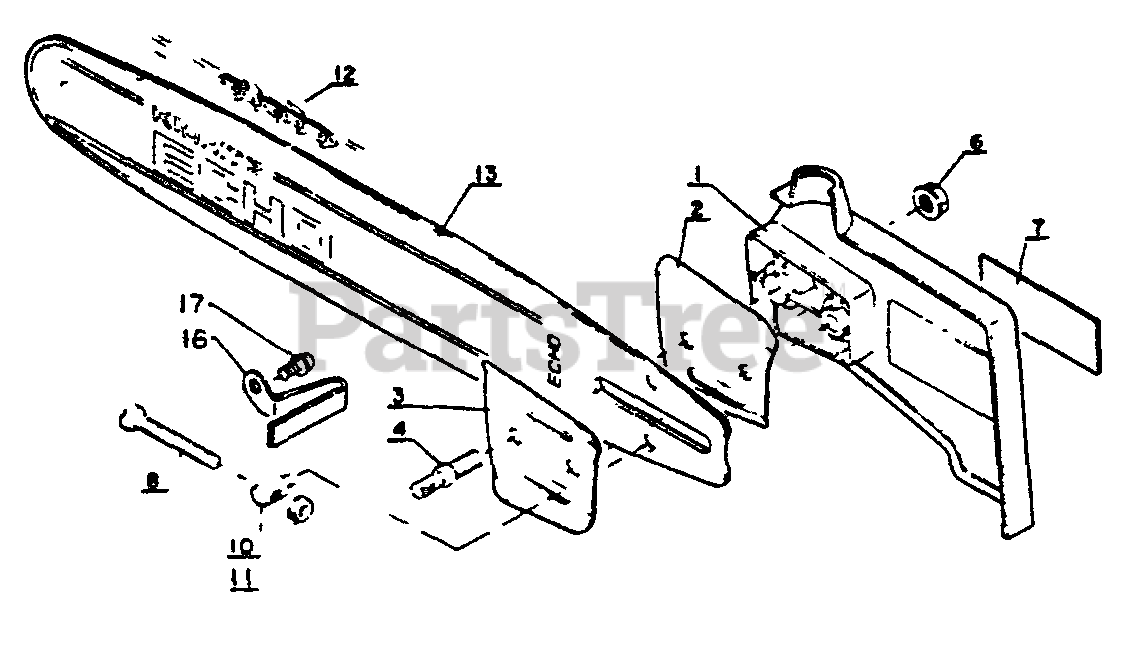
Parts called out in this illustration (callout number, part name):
1	COVER, GUIDE BAR
2	PLATE, GUIDE - OUTER
3	PLATE, GUIDE - INNER
4	STUD, GUIDE BAR
6	NUT - 6 -- FLANGE
7	LABEL - ECHO
8	SCREW, TENSIONER
10	TENSIONER, CHAIN
11	LOCKNUT - 5
16	CATCHER, CHAIN
17	SCREW - 5X10
